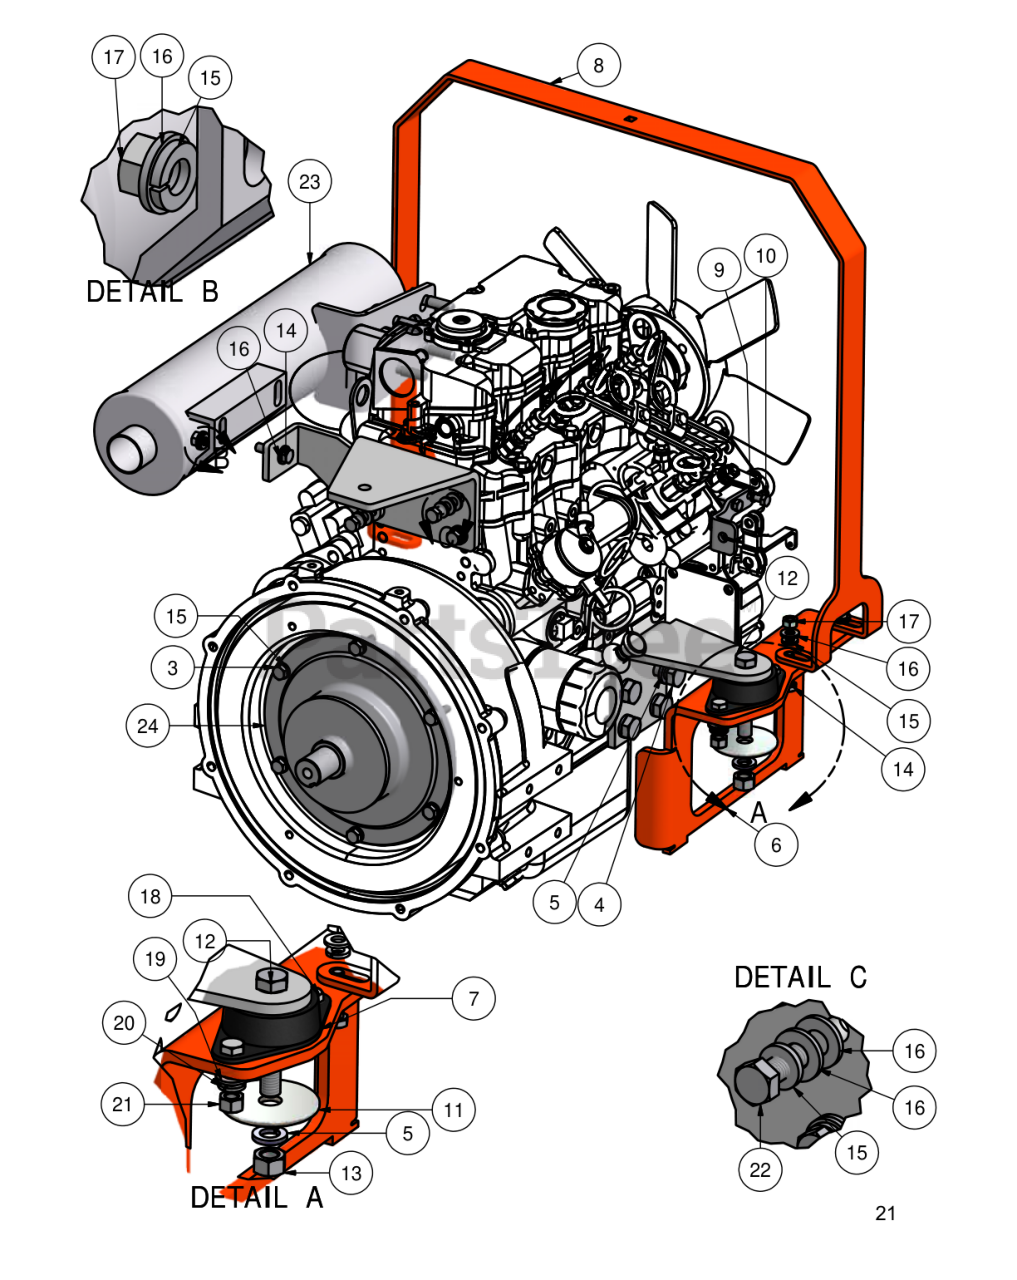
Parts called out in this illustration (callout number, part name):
1	35hp Caterpillar Engine
2	5/16" x 1" Bolt
3	12mm x 25mm Bolt
4	1/2" Lock Washer
5	28hp Diesel Frame
6	35hp Diesel Frame
7	Rubber Isolator
8	Hood Holder
9	1/4" Lock Washer
10	6mm x 20mm Bolt
11	Snubbing Washer
12	1/2" x 3" Hex Bolt
13	1/2" Hex Nut
14	5/16" x 1 1/4" Hex Bolt
15	5/16" Lock Washer
16	5/16" Flat Washer
18	3/8" x 1" Hex Bolt
19	3/8" Flat Washer
20	3/8" Lock Washer
21	3/8" Hex Nut
22	8mm x 25 Bolt
23	Diesel Muffler
24	Stub Shaft
